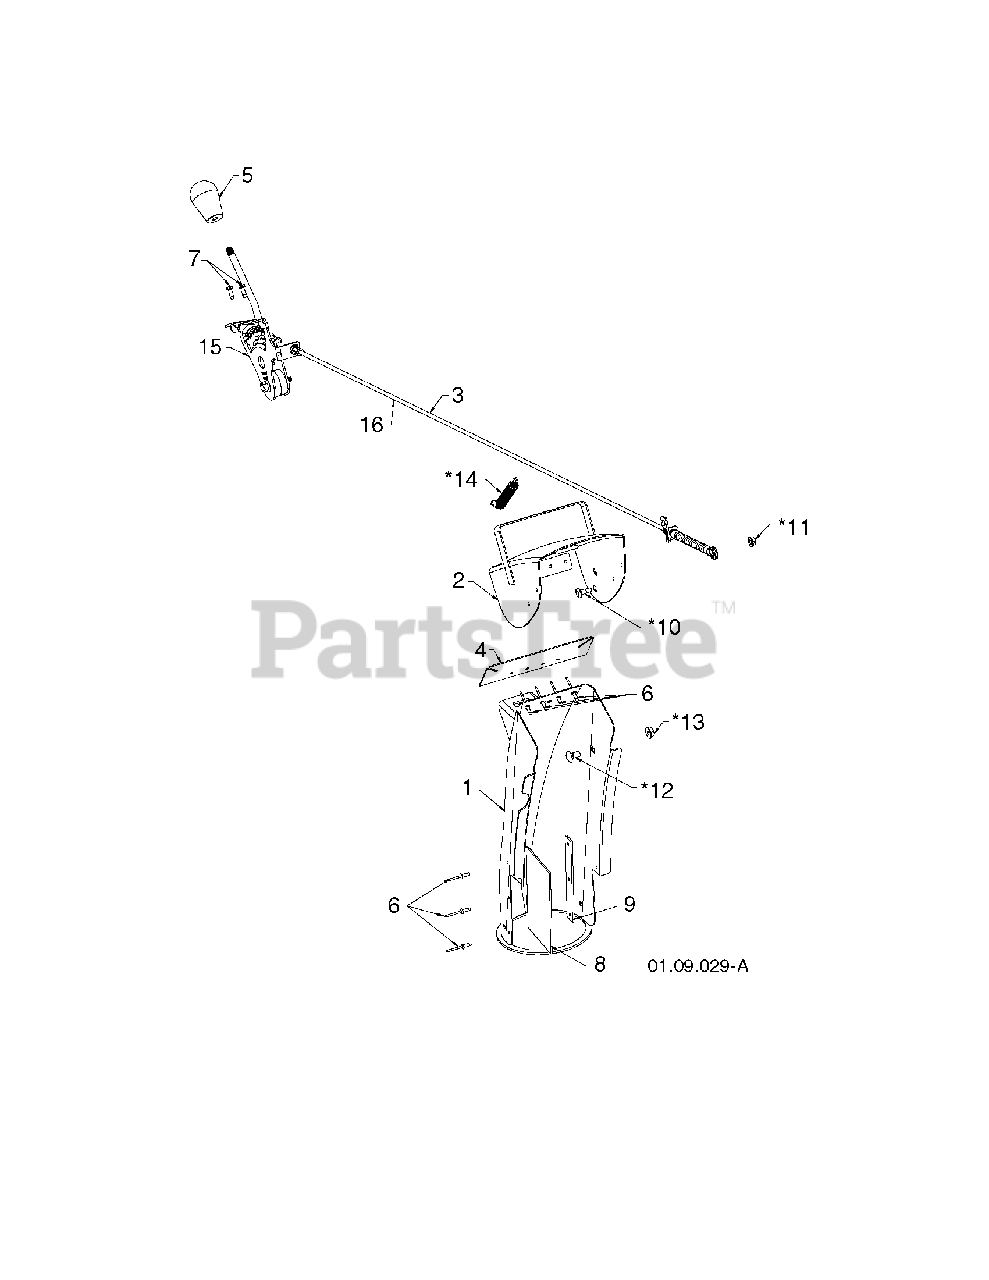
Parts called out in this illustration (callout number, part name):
1	RP_CHUTE.WELDMENT.SNOW.ORANGE
2	DEFLECTOR.WELDMENT.PNT.ORANGE
3	RP.CONTROL.ASM.DEFLECTOR.SNOW
4	SEAL.DEFLECTOR
5	KNOB.OVERMOLD.DS.HUSQVARNA/BLK
6	RIVET BLIND
7	SCREW #10-24 X 5/8
8	SHIELD.SNOW.CHUTE
9	STRAP.SHEILD.RETAINER
10	BOLT, SHOULDER
11	NUT.HEX.FLANGE.1/4
12	BOLT
13	NUT.LOCK.5/16-18
14	SPRING.DEFLECTOR.REM.CHUTE
15	RP CNTRL.HEAD.ASSEM.DEFLECTOR
16	RB SERVICE.CHUTE.DEF.CBL.BLK
